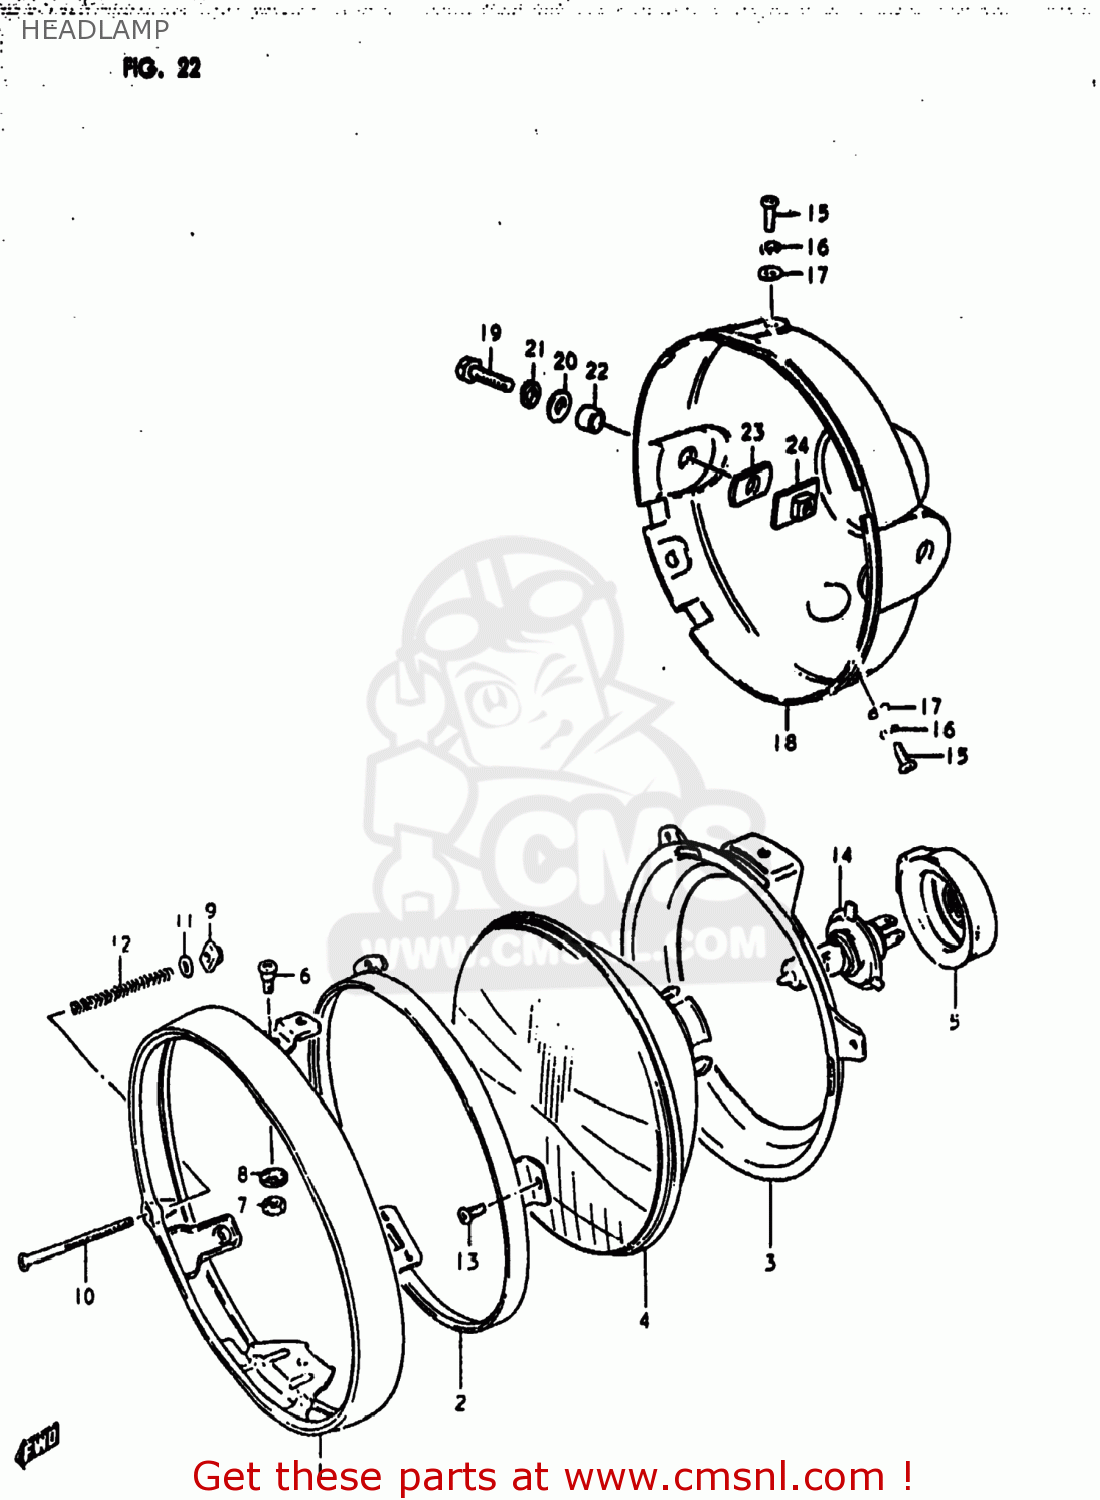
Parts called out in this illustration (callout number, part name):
1	RIM
2	RETAINER
3	RING,HEADLAMP UNIT
4	LAMP UNIT
5	COVER,HEADLAMP SOCKET
6	SCREW
7	NUT,ADJUSTING
8	SPACER
9	NUT
10	SCREW,HEADLAMP ADJUST
11	WASHER
12	SPRING,HEADLAMP ADJUST
13	SCREW
14	BULB(12V60/55W,H4)
15	SCREW
16	WASHER,LOCK
17	WASHER
18	HOUSING,HEADLAMP(BLACK)
19	BOLT
20	WASHER
21	LOCK WASHER
22	SPACER (8.8X12X7)
23	CUSHION
24	PLATE,HEADLAMP HOUSING
